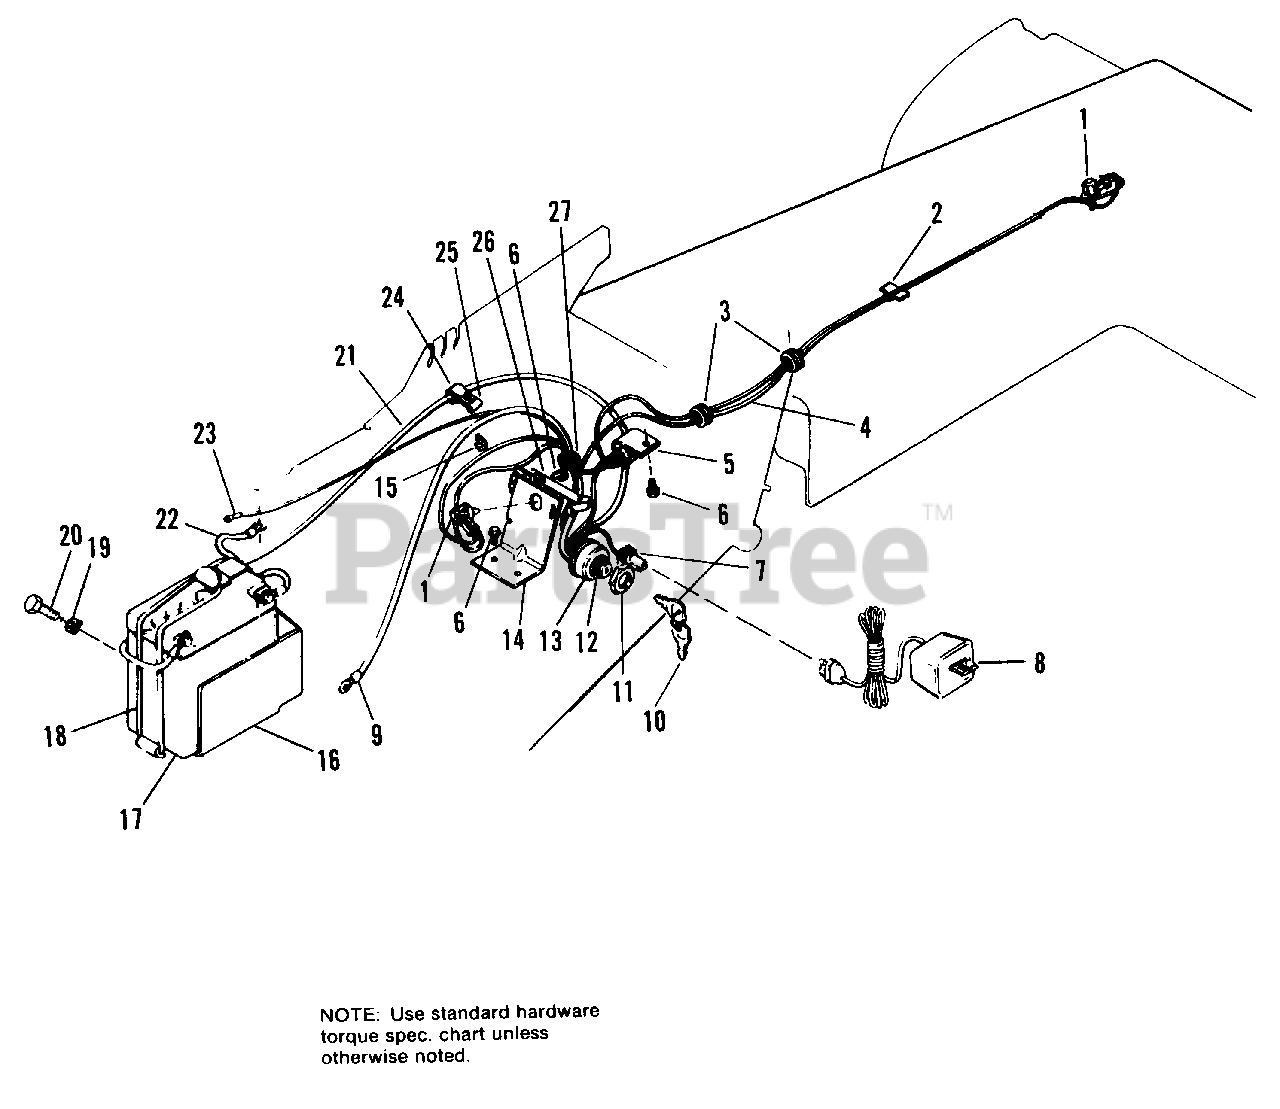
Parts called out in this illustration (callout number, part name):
4	WIRE, Green
5	INTERLOCK
6	SCREW, Hex, Washer Hd., Taptite, 1/4-20 x 3
7	RECEPTACLE, Charger
8	CHARGER, Battery
9	CABLE ASSY. (Switch to Start)
11	NUT, Hex, Special
12	LOCKWASHER, 5/8
13	SWITCH, Ignition
14	SWITCH, Support
15	SCREW, Hex, Washer Hd., Taptite, 1/4-20 x 3/8
16	SUPPORT ASSY., Battery
17	BATTERY & CLIP ASSY.
18	STRAP, Rubber
19	NUT, Speed
20	SCREW, Self Tapping, #10 x 1/2
21	CABLE ASSY. (Battery pos. to ignition switch)
22	CABLE ASSY. (Battery neg. to ground)
23	WIRE, Black
25	CLIP, Cable
